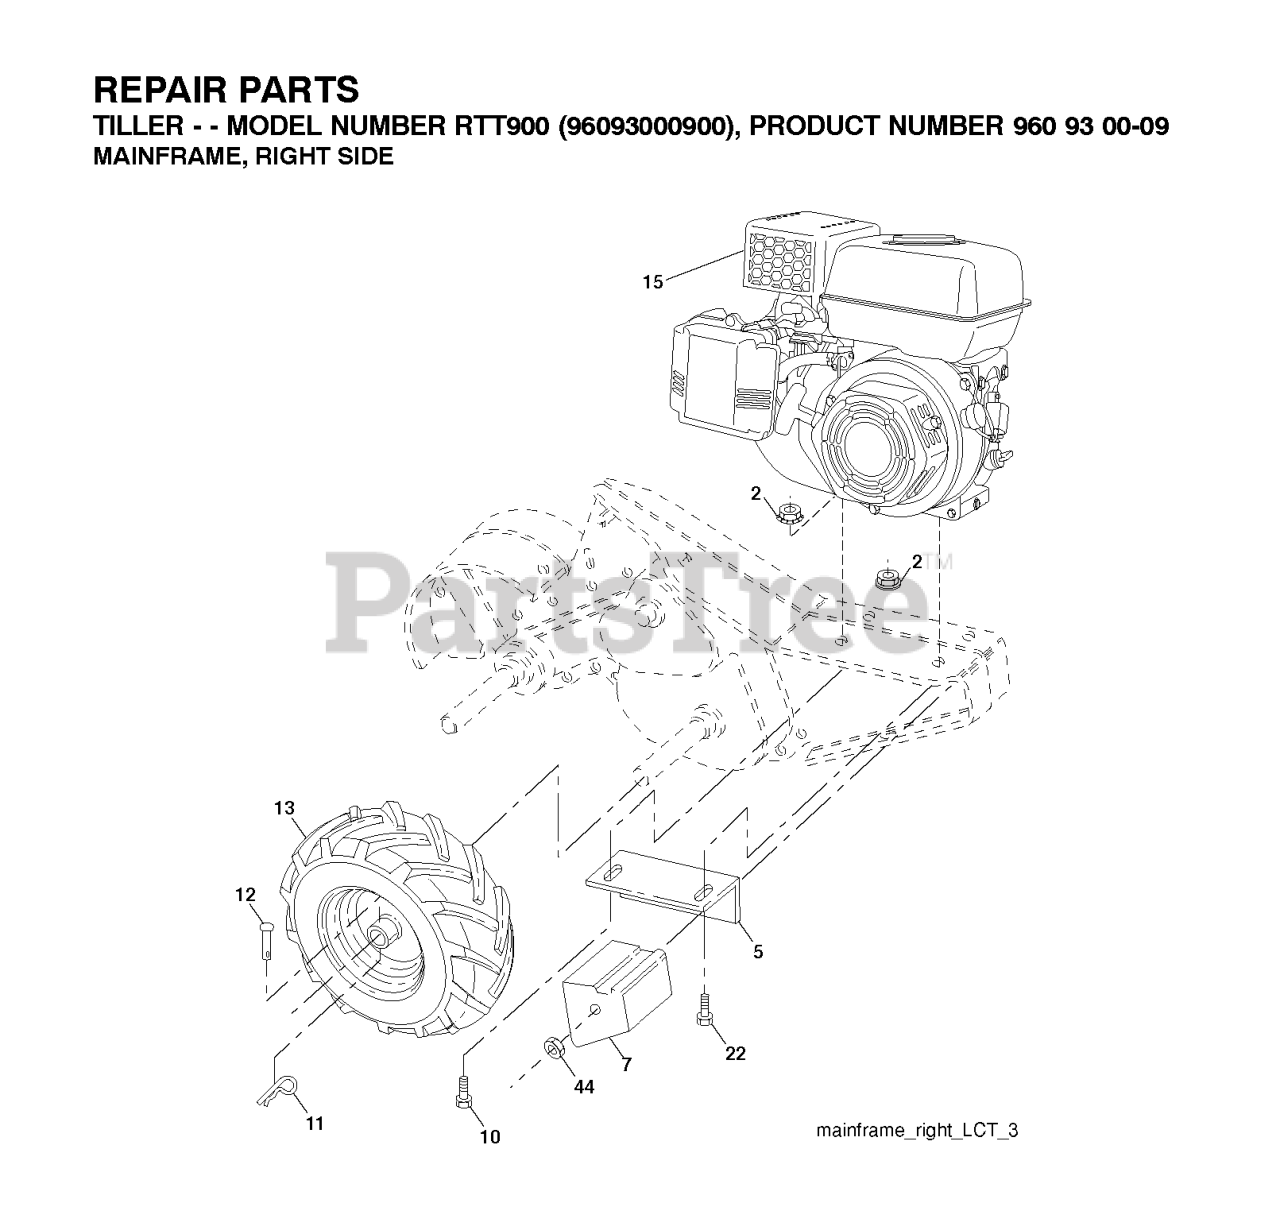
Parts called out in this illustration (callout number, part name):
2	LOCKNUT-FLANGE 5/16-18
5	DNO BRACKET RH CRT
7	COUNTERWEIGHT, RH
10	BOLT
11	RETAINER M
12	RIVET,DRILLED
13	VALVE STEM LT
13	RIM.ASM.6".SILVER
13	TIRE.13X5-6.CHEVRON.TILLER
22	BOLT
